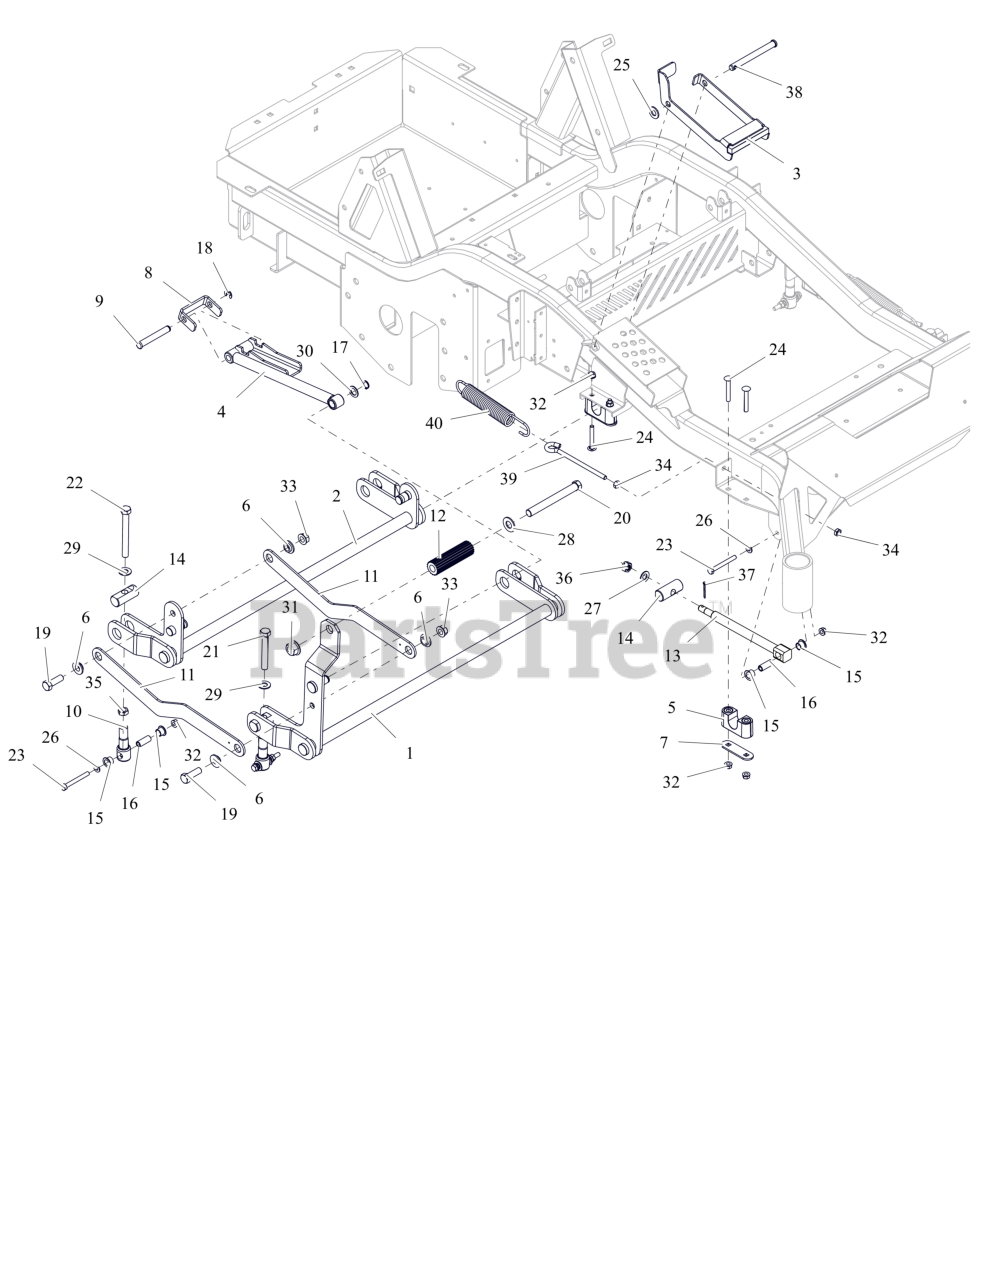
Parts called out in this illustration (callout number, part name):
1	WLDMT, FRONT DECK LIFT PIVOT
2	WLDMT, REAR DECK LIFT PIVOT
3	WLDMT, HOC TRANSFER LOCK (BLACK)
4	WLDMT, HOC LIFT ARM (BLACK)
5	ASM-BUSHING, DECK LIFT
6	BSHG-FLG .515X.750X.310X1.120
7	PLATE, BEARING SUPPORT
8	BRKT, HOC LINE
9	PIN, .499/.494 x 3.385 CLEVIS
10	LINK, DECK LIFT FORMED
11	LINK, DECK
12	ROD, FOOT PEDAL (BLACK)
13	DRAG,LINK-HD
14	PIN, DECK LIFT
15	BSHG, FLANGED .50X.625X.50X.062
16	SPCR, .31X.50X1.265
17	RG-RTNG-EXT .625X.050
18	RG-RTNG-EXT .500X.042 (E)
19	BLT,HEX .50-13X1.50 G5 ZCC
20	BLT, HEX .62-11X5.50 G5 FBP
21	BLT, HEX 0.5-13X3.5F GR5 ZCC
22	BLT, HEX .50-13X4.50F G8 ZCC
23	BLT, HEX .31-18X2.75 G5 ZCC
24	BLT, RHSSN.31-18X2.25 G5 ZCC
25	WSHR,FLT .531X1.062X.095 ZCC
26	WSHR,FLT .344X.688X.065 ZCC
27	WSHR, BLVL .505 X 1.000 X .073 ZCC
28	WSHRFLT 5/8SAE CARBHARD FBP
29	WSHR, FLT .557X1.040X.102 ZCC
30	WSHR, FLT .630X1.005X.062 ZCC
31	NUT,FLG-TOP LK .625-11 FBP
32	NUT,LK-CTR-FLG .31-18 GF ZCC
33	NUT-LK-CTR-FLG .500-13 GG ZCC
34	NUT-JAM .375-16 G2 ZCC
35	NUT-JAM .500-13 G2 ZCC
36	NUT-SL .50-13
37	PIN,CTR.12X1.25EXTPRSQCT ZC120
38	PIN, SLIC-.500X4.97X4.55 -ZC
39	BOLT,.38-16 X 5.25-.62 DIA EYE
40	SG-TENS .162X1.25X8.25 WLD 25
